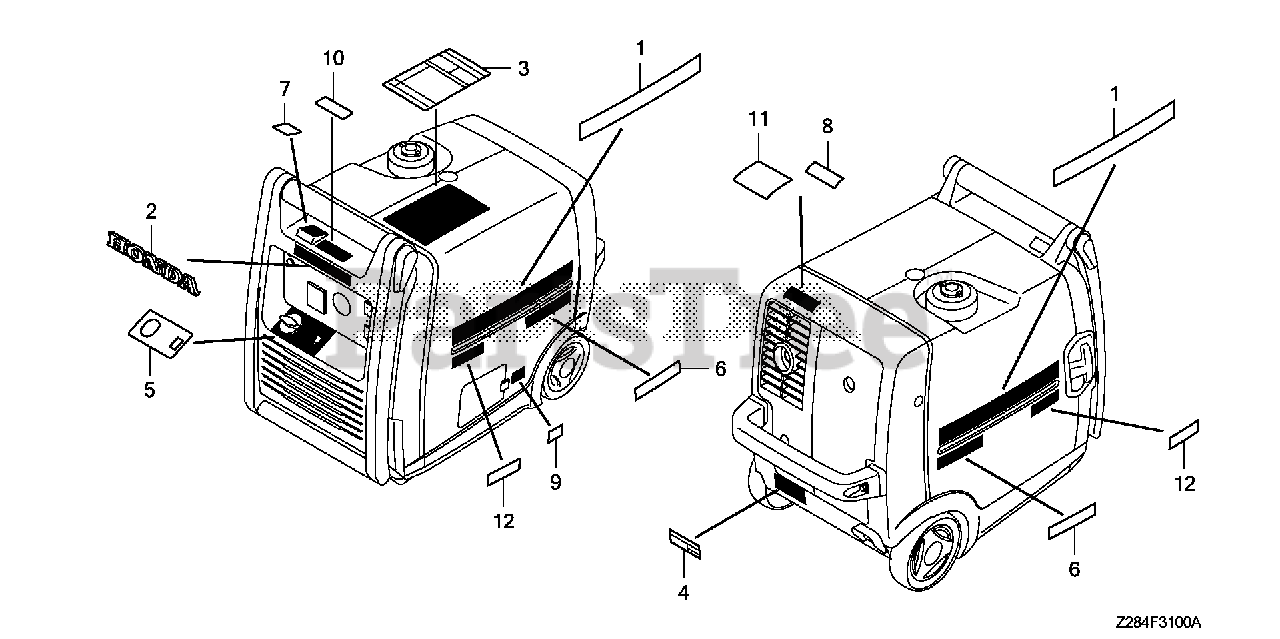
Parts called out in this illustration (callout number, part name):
1	MARK, EMBLEM (EU3000I)
2	MARK, HONDA
3	MARK, CAUTION
4	MARK, SPEC
5	MARK, ENGINE SWITCH
6	MARK, HONDA
7	MARK, INDICATOR
8	MARK, EX. CAUTION
9	MARK, OIL CAUTION
